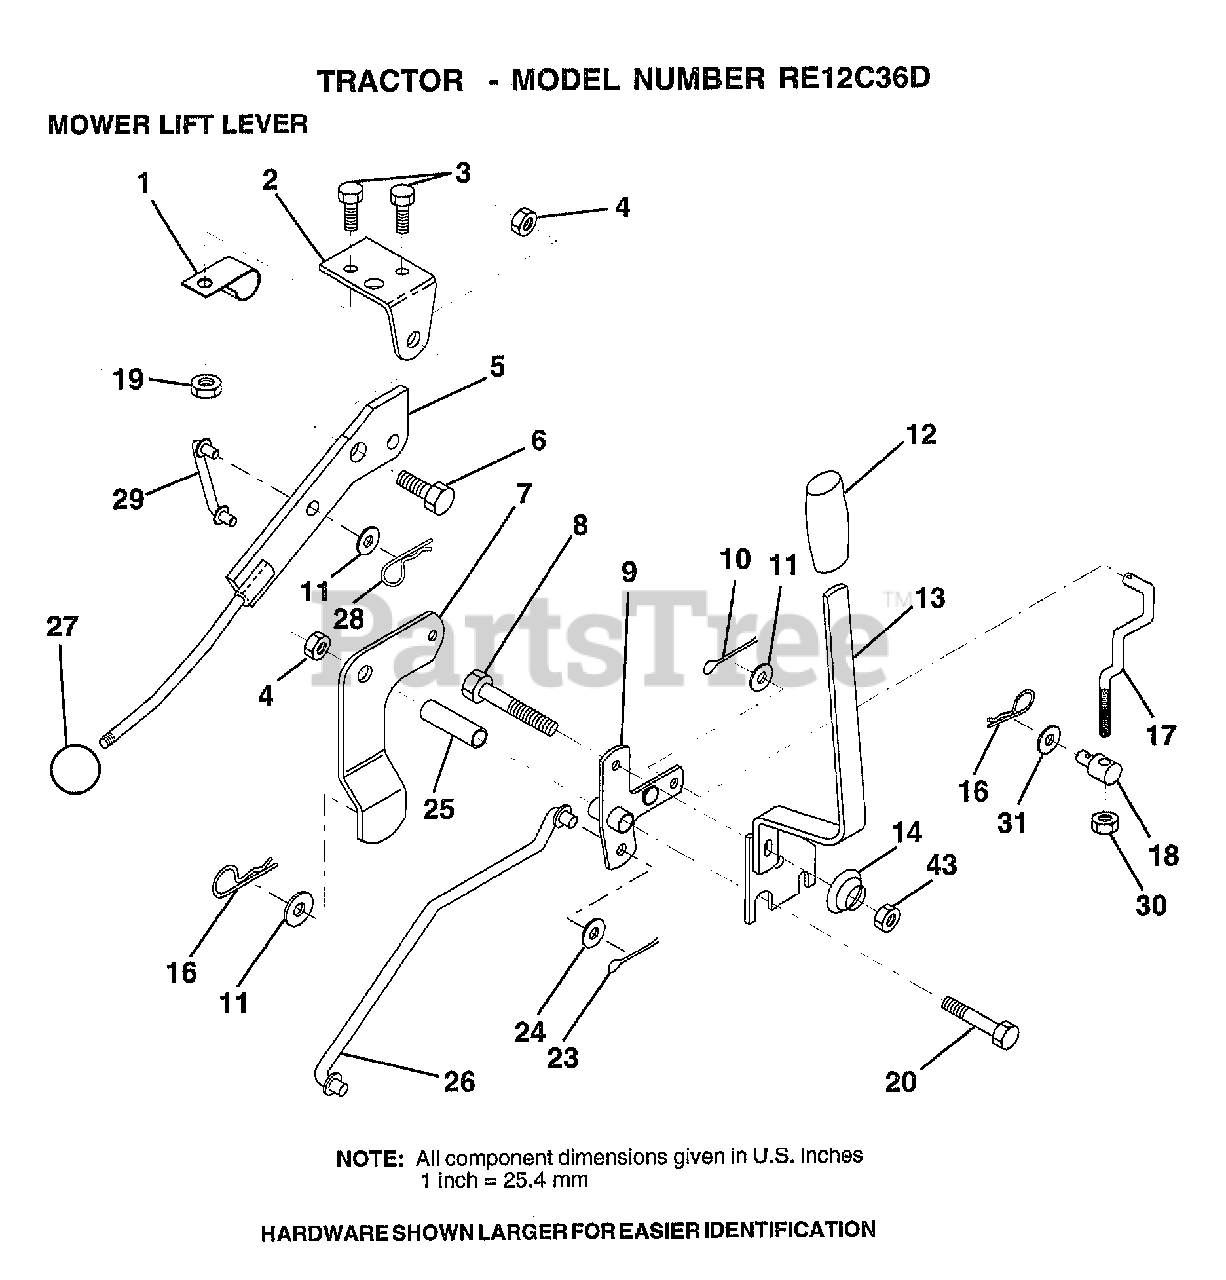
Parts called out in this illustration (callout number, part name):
1	"CLIP,INSULATOR"
2	BRKT CLUTCH
3	BOLT HXHD FIN
5	LEVER.ASM.CLUTCH
6	"BOLT, SHOULDER LT"
7	MWR CLUTCH ARM AS
8	BOLT
9	"BELLCRANK,LIFT"
10	COTTER PIN
11	WASHER
13	HANDLE.ASM.LIFT
14	SPRING COMPRESSIO
16	SPRING.RETAINER
17	"LINK,LIFT FRT"
18	TRUNION ADJ
20	BOLT
23	PIN COTTER 1/8
25	TUBE SPACER
26	ROD LIFT MOWER
27	KNOB T(3/8 HOLE)
28	RETAINER M
29	CLUTCH LINK
30	NUT
31	WASHER
